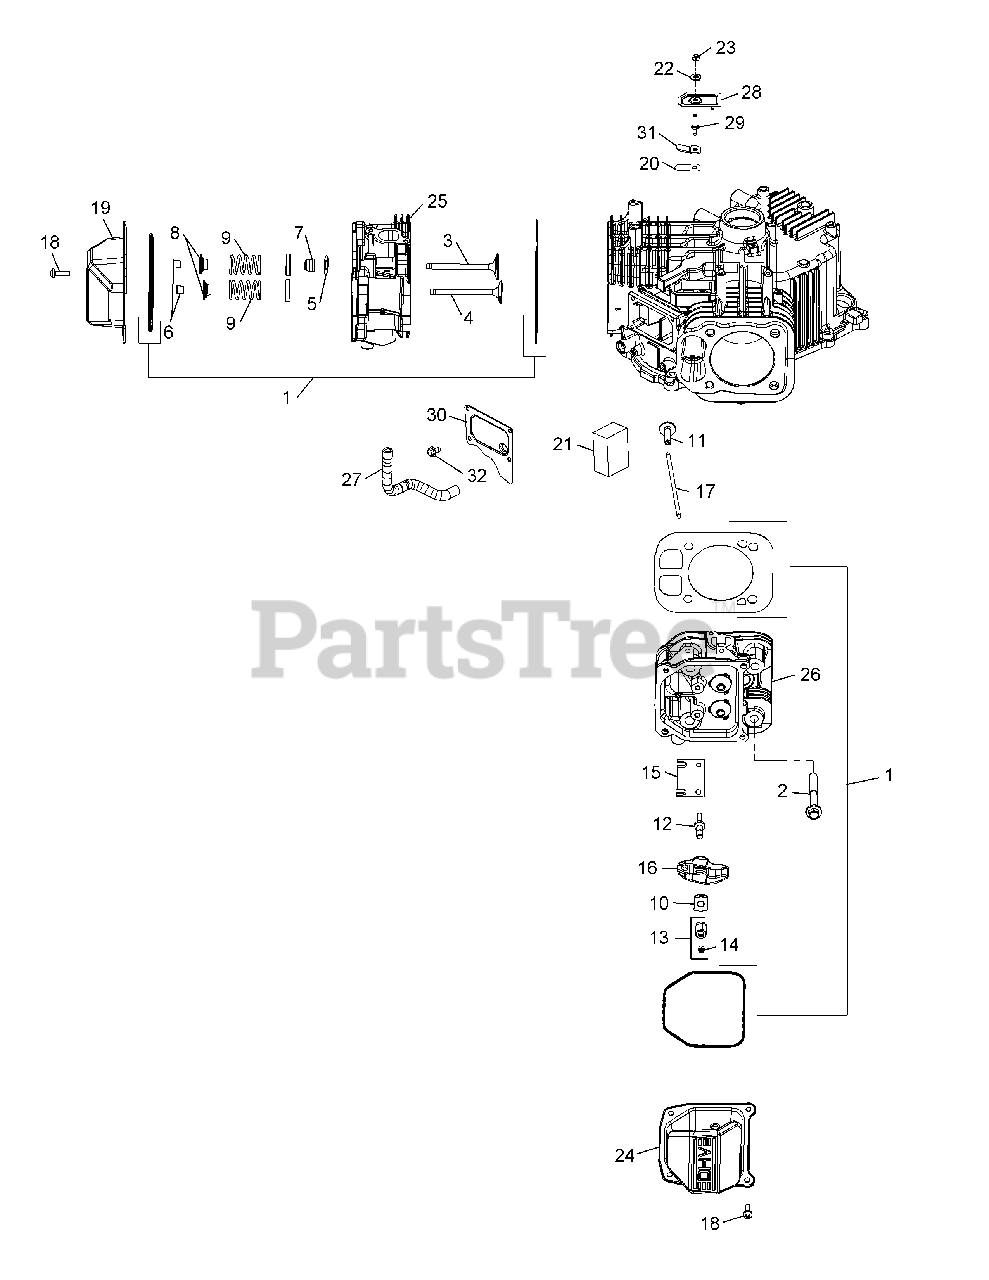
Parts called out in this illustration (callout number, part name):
1	Cylinder Head Gasket Kit
2	Flange Screw, M10 x 1.5 x 90
4	Exhaust Valve
5	Spacer (.010")
6	Retainer Kit
7	Valve Band Seal
8	Valve Spring Cap
9	Valve Spring
10	Rocker Arm Pivot
13	Hex Nut Assembly (Inc. #14)
18	Pan Head Screw
20	Breather Reed
21	Breather Filter
22	Sealing Washer
23	Lock Nut, M5 x 8
24	Rocker Cover
25	Cylinder Head Assembly Kit, #1
26	Cylinder Head Assembly Kit, #2
27	Breather Hose
28	Breather Cover
30	Breather Media Cover
31	Reed Retainer
32	Thread Forming Screw
